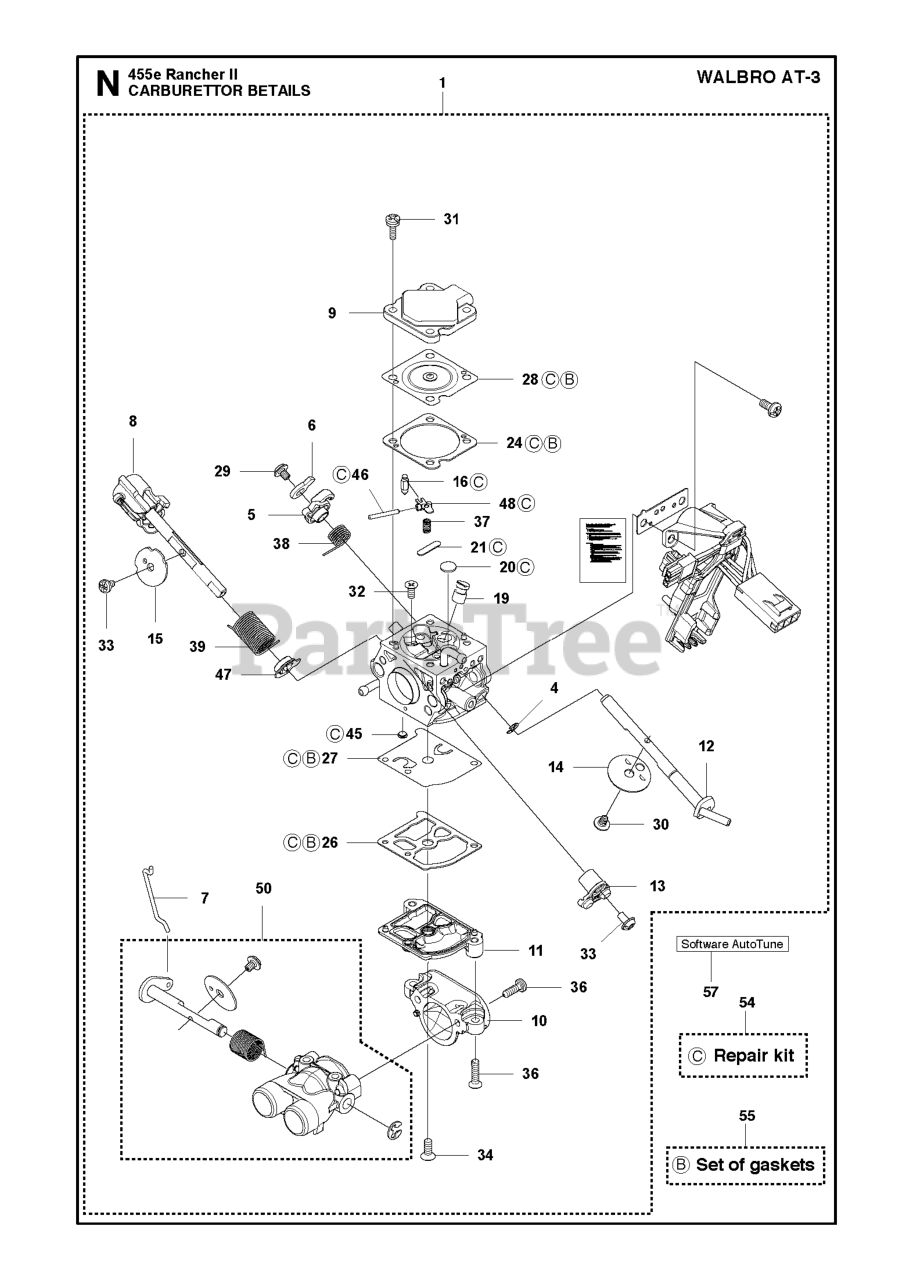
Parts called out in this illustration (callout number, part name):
1	CARBURETOR
8	THROTTLE LEVER
12	SHAFT ASSY
13	THROTTLE SHAFT
15	THROTTLE VALVE
16	INLET NEEDLE
19	MAIN NOZZLE
20	PLUG WELCH
28	DIAPHRAGM ASSY
30	SCREW
45	FUEL INLET SCREEN
46	FULCRUM PIN
50	THROTTLE VALVE ASSY
54	REPAIR KIT
55	GASKET KIT
